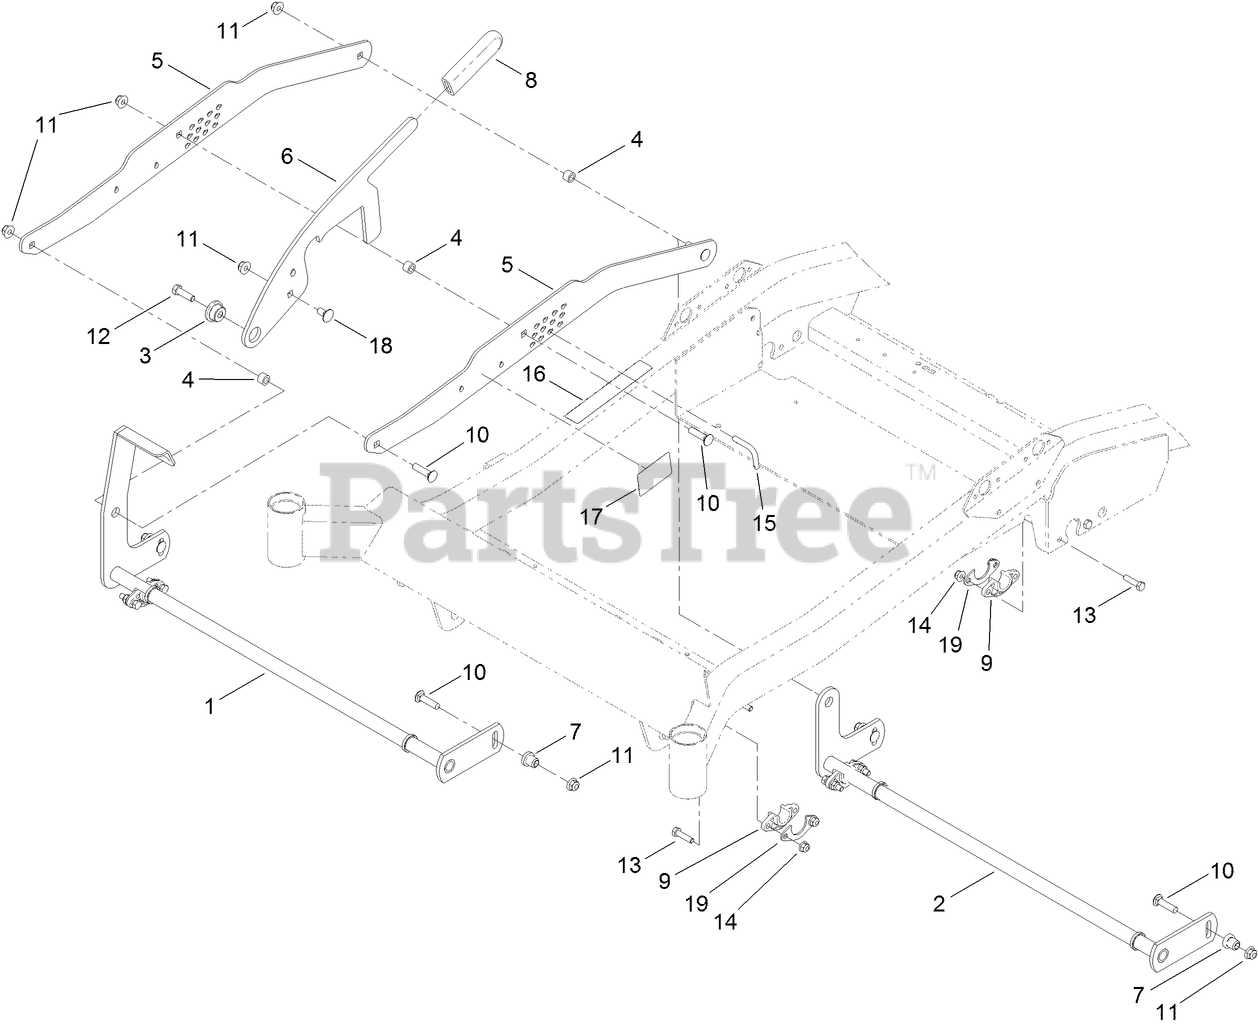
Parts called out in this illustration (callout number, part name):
1	PIVOT-FRONT
2	PIVOT-REAR
3	BUSHING-MOUNT, HOC
4	SPACER
5	PLATE-LIFT, FOOT
6	PLATE-STOP, HOC
7	BUSHING-PULLEY
8	GRIP-LEVER
9	BUSHING-FLANGE
10	SCREW-CARR
11	NUT-HF, NI
12	SCREW-HH
13	SCREW-HH
14	NUT-HF, NI
15	PIN-KEYED
16	DECAL-HOC
17	DECAL-LOCK, DECK
18	SCREW-CARR
19	GUSSET-LIFT, DECK
